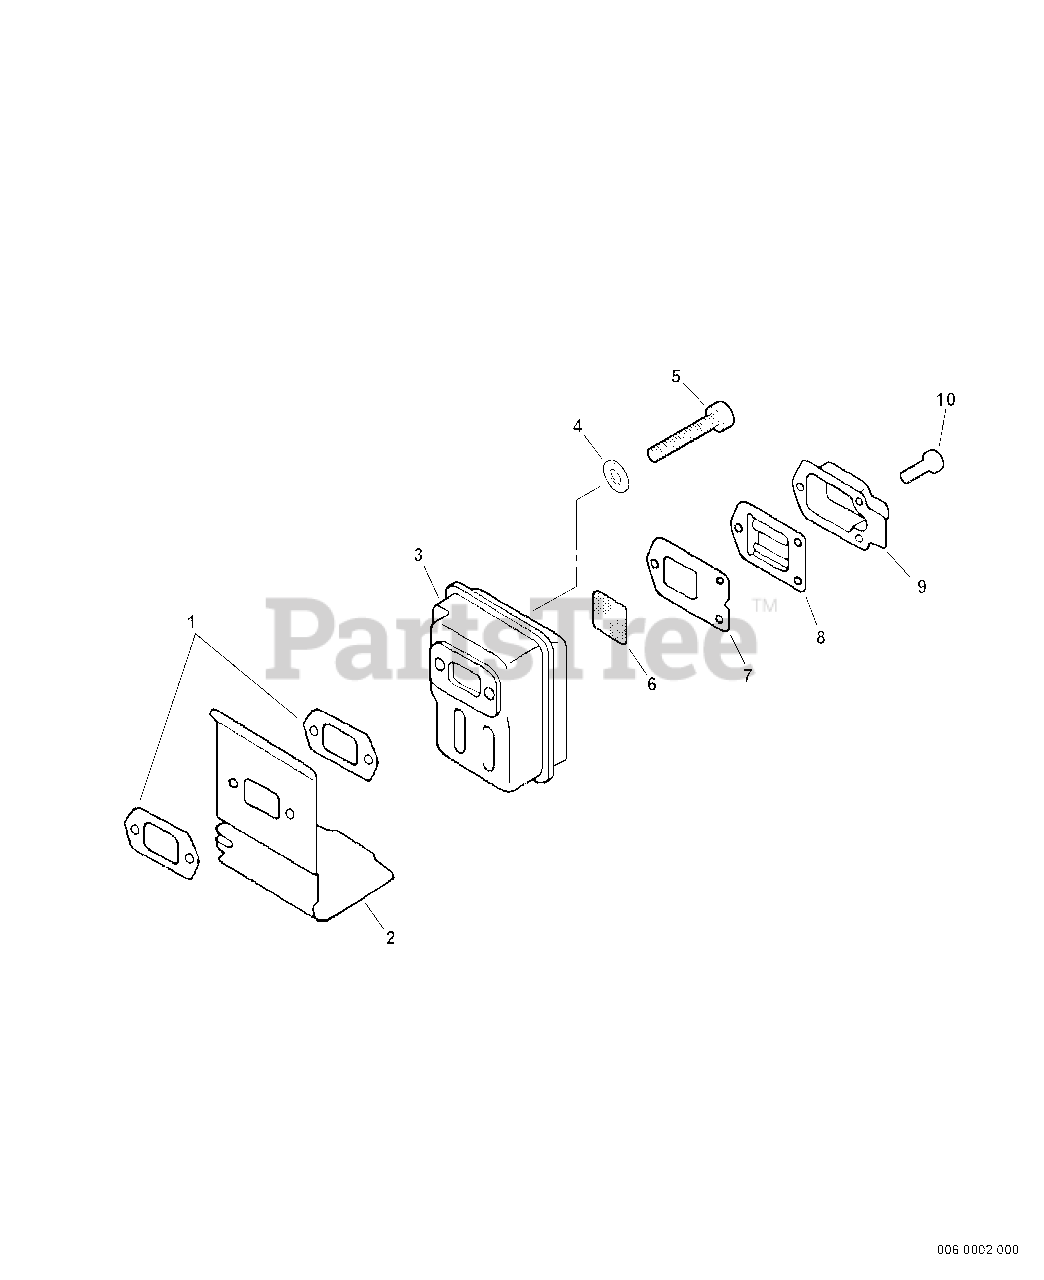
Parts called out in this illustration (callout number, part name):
1	GASKET, EXHAUST
2	SHIELD, EXHAUST
4	WASHER - 5
5	SCREW - 5X55
6	SCREEN, SPARK ARRESTOR
7	GASKET, EXHAUST
8	GASKET, EXHAUST - INNER
9	GUIDE, EXHAUST - OUTER
10	SCREW - 4X10
